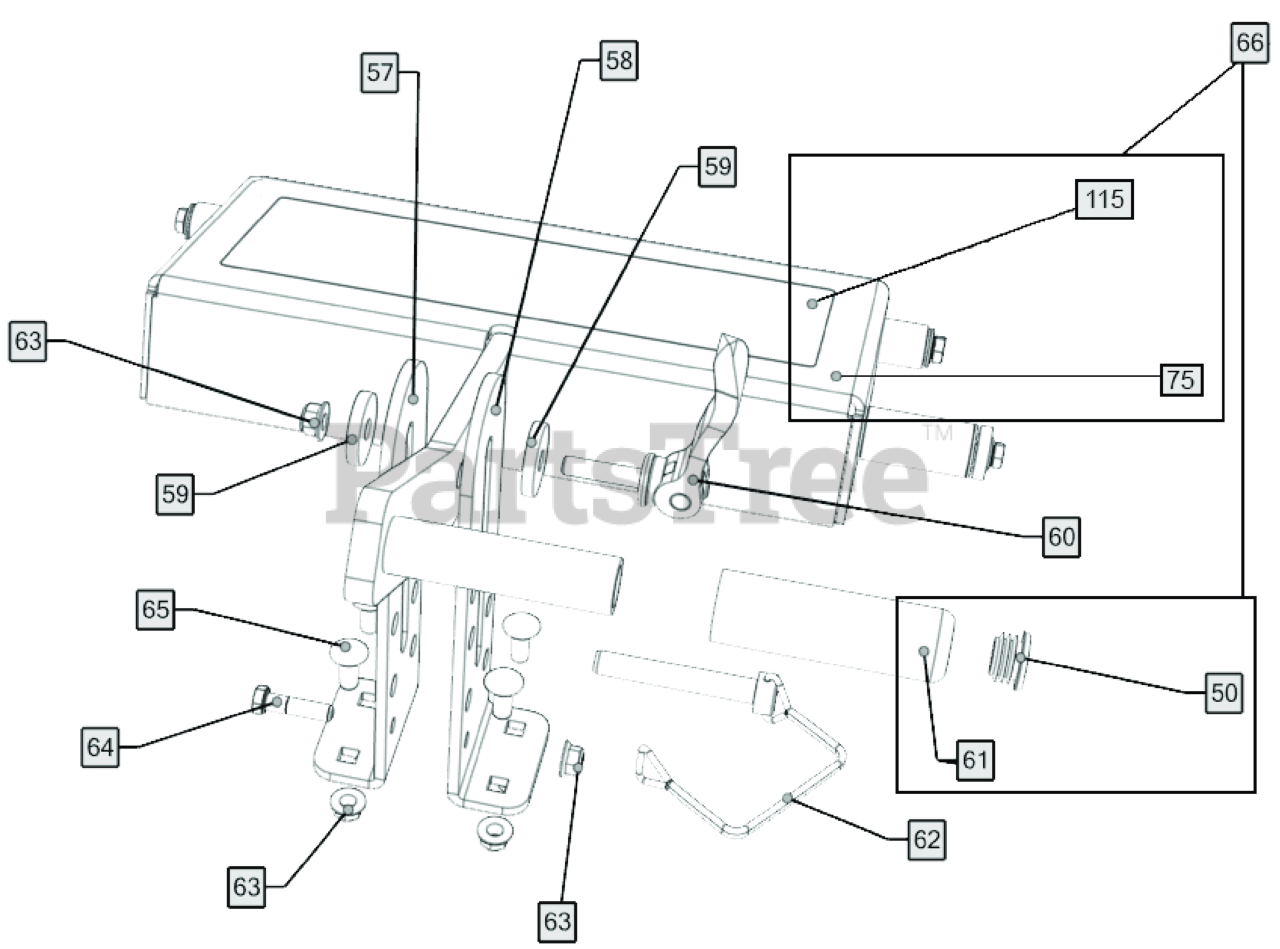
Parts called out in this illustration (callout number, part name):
50	PLUG TUBE INSERT 1" OD
57	BRACKET, DEPTH CONTROL LH
58	BRACKET, DEPTH CONTROL RH
59	WASHER 1.5 OD X .453 ID X .25 THK
60	LEVER CAM LOCK
61	GRIP 1" ID X 4"
62	PIN, WIRE LOCK 1/2 X 3" LG ZP
63	NUT-HEX-NYLK, FLG .375"-16 ZP
64	SCREWCAP 3/8"-16 X 1 3/4" HCS ZP
65	BOLT CARRAIGE 3/8-16 X 1" ZP
66	BRACKET HEIGHT ADJUST W/ LABELS
75	BRACKET, HEIGHT ADJUST WA
115	LABEL, BADGING TOP
